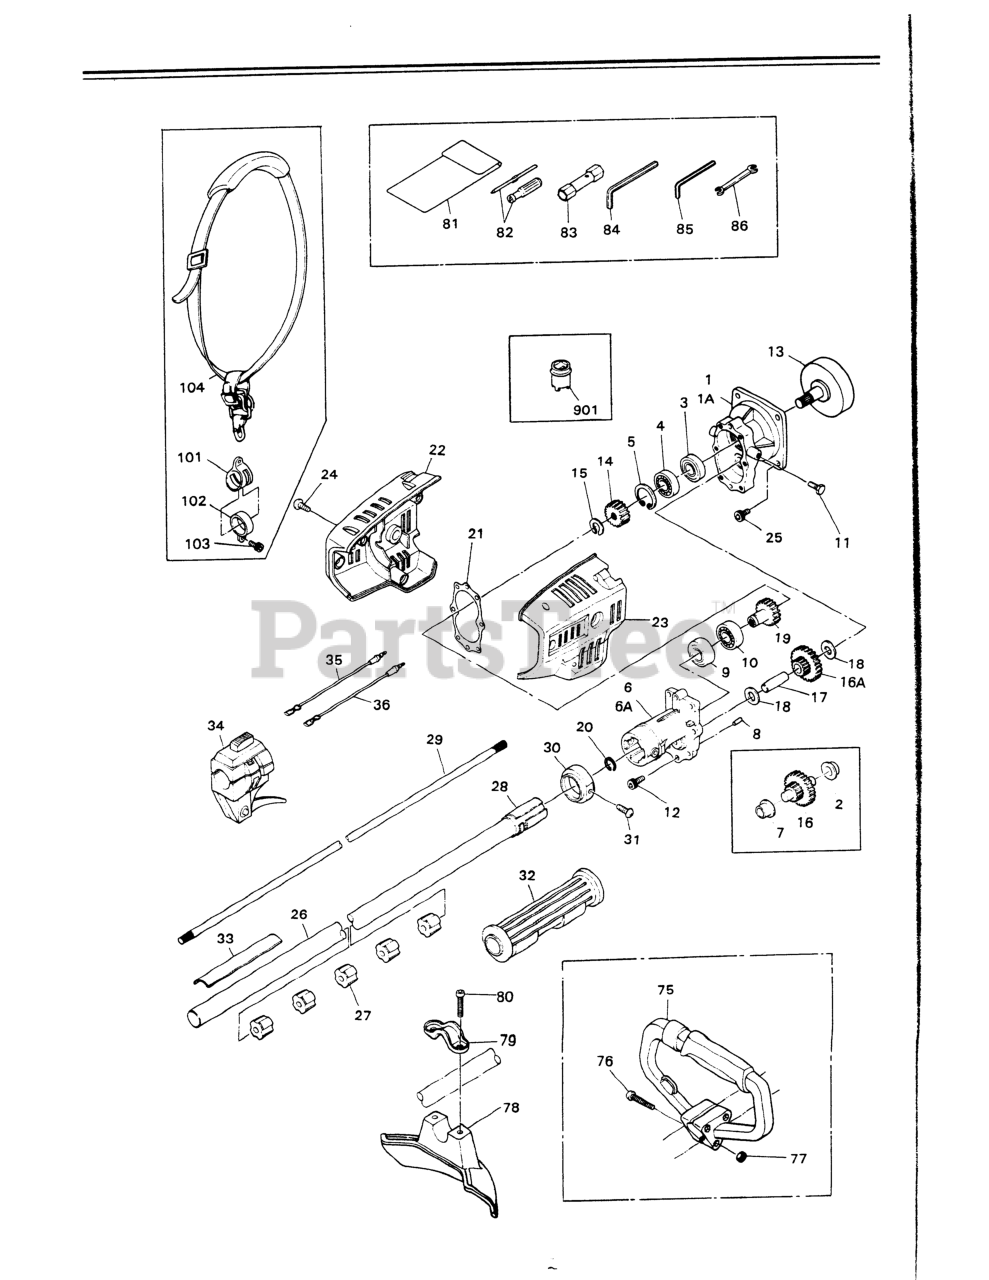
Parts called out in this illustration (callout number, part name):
1	CASE-R-C
1A	CASE (R) (NO LONGER AVAIL)
3	BEARING
4	BEARING
5	RING, SNAP, M28 x 1.2
6	CASE-P-C
6A	CASE, FRONT
8	PIN, DOWELL
9	BEARING
10	BEARING
11	BOLT, M6 x 8
12	BOLT, M5 X 20
13	DRUM
14	GEAR, PINION
15	RING, SNAP
16A	GEAR (RPLS 3805-11330)
18	WASHER
19	GEAR, WHEEL
22	COVER, RIGHT (RPLS. -11510)
23	COVER, LEFT (RPLS -11520)
29	SHAFT
30	CAP
31	SCREW, M5 X 10
35	CORD-A, BLACK
36	CORD-B, RED
75	HANDLE (RPLS -14310)
76	SCREW, M5 x 30(RPLS 0263-00530
77	NUT, M5 X 4
79	CLAMP (REPLACES 5807-24120)
80	BOLT, M6 x 1.30
82	SCREWDRIVER
84	WRENCH (TOOL)
85	WRENCH (TOOL)
86	SPANNER, 8 X 10 (RPLS 2540- )
101	HANGER (USE -18101)
103	SCREW, M5X20 (RPLS.1400-75510)
901	SOCKET(NO LONGER AVAILABLE)
NI	TOOL SET
